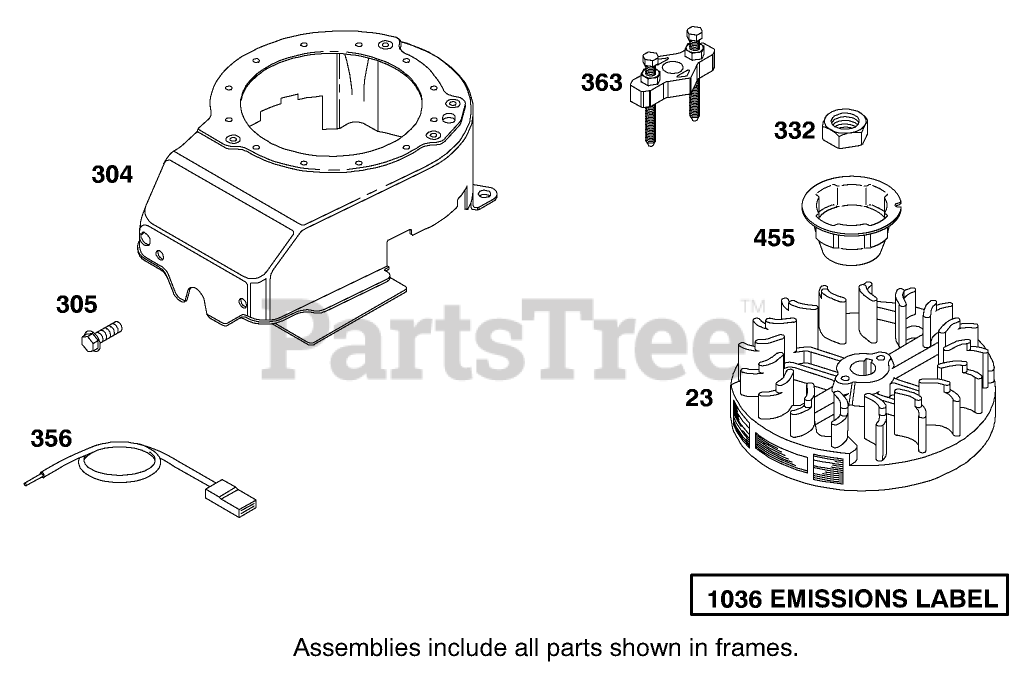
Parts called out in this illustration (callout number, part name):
23	Flywheel
304	Housing-Blower
305	Screw
332	Screw
356	Wire-Stop
363	Puller-Flywheel
455	Cup-Flywheel
1036	Label-Emissions
